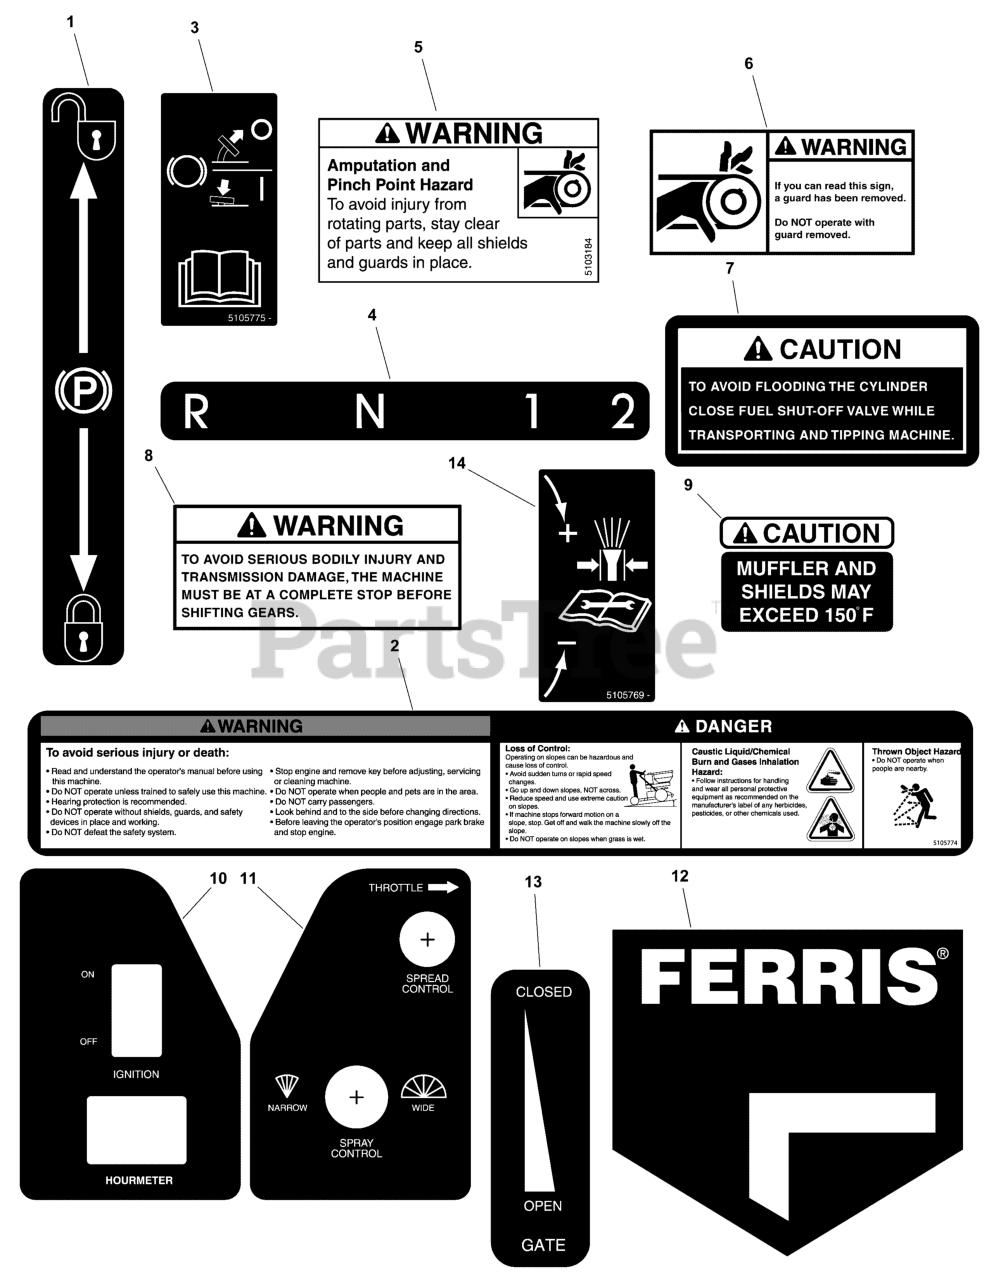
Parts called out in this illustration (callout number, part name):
1	DECAL, PARKING BRAKE SYMBOLS
2	DECAL, WARNING / DANGER
3	DECAL, BRAKE PEDAL
4	DECAL, GEAR SELECTOR
5	DECAL, WARNING, HAND IN BELT, ENG ONLY
6	DECAL, WARNING, GUARD
7	DECAL, CAUTION, FLOODING
8	DECAL, WARNING, INJURY & TRANS. DAMAGE
9	DECAL, CAUTION, MUFFLER TEMP.
10	DECAL, PATHFINDER LEFT CONSOLE
11	DECAL, PATHFINDER RIGHT CONSOLE
12	DECAL, 3.00" FERRIS SHIELD LOGO
13	DECAL, PATHFINDER GATE LEVER
14	DECAL, COMBO SPRAY CONTROL
